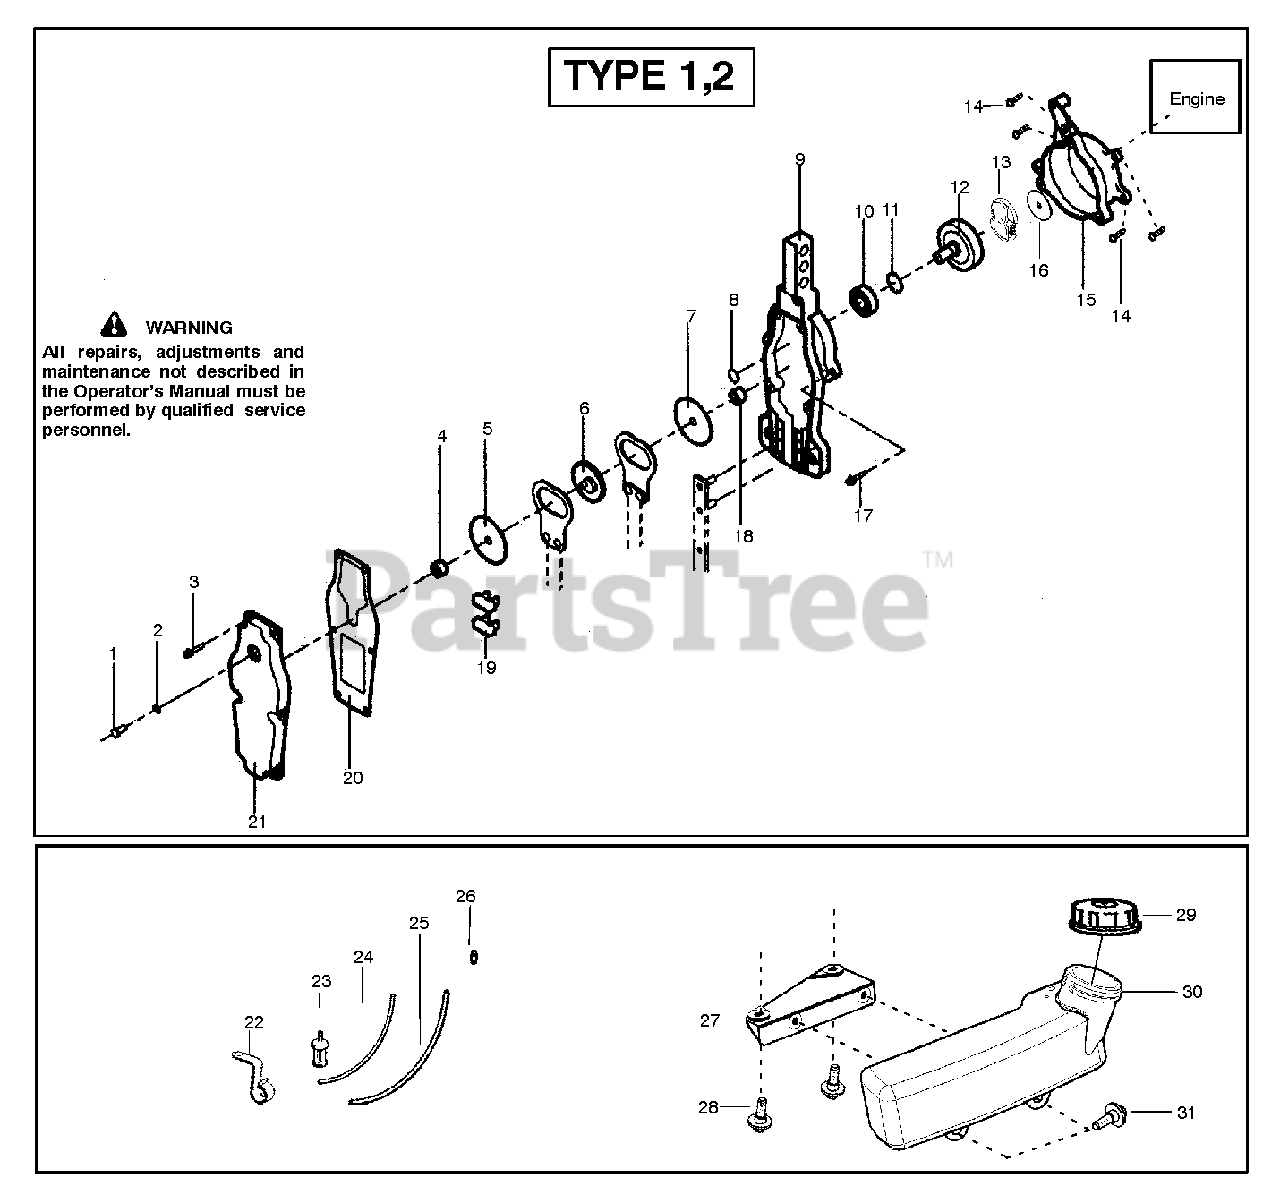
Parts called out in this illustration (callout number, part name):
3	SOCKET SCREW FLANGE KAAZ
4	BUSHING KAAZ
8	C-SNAPPING FOR SHAFT KAAZ
11	C-SNAPPING KAAZ
13	CLUTCH ASSY
14	SCREW-10-14 X 13/16 (PL
16	FRICTION DISC,CLUTCH 36/41
17	SOCKET SCREW FLANGE KAAZ
18	BUSHING KAAZ
19	FELT PACKING KAAZ
20	PACKING KAAZ
23	FUEL PICK-UP ASSY
24	KIT-LINE
25	LINE KIT
26	FUEL LINE FITTING
28	SCREW FUEL TANK RETAINER
29	ASSY - FUEL CAP W/RETAINER
30	ASSY FUEL TANK (FL)
31	RETAINER
